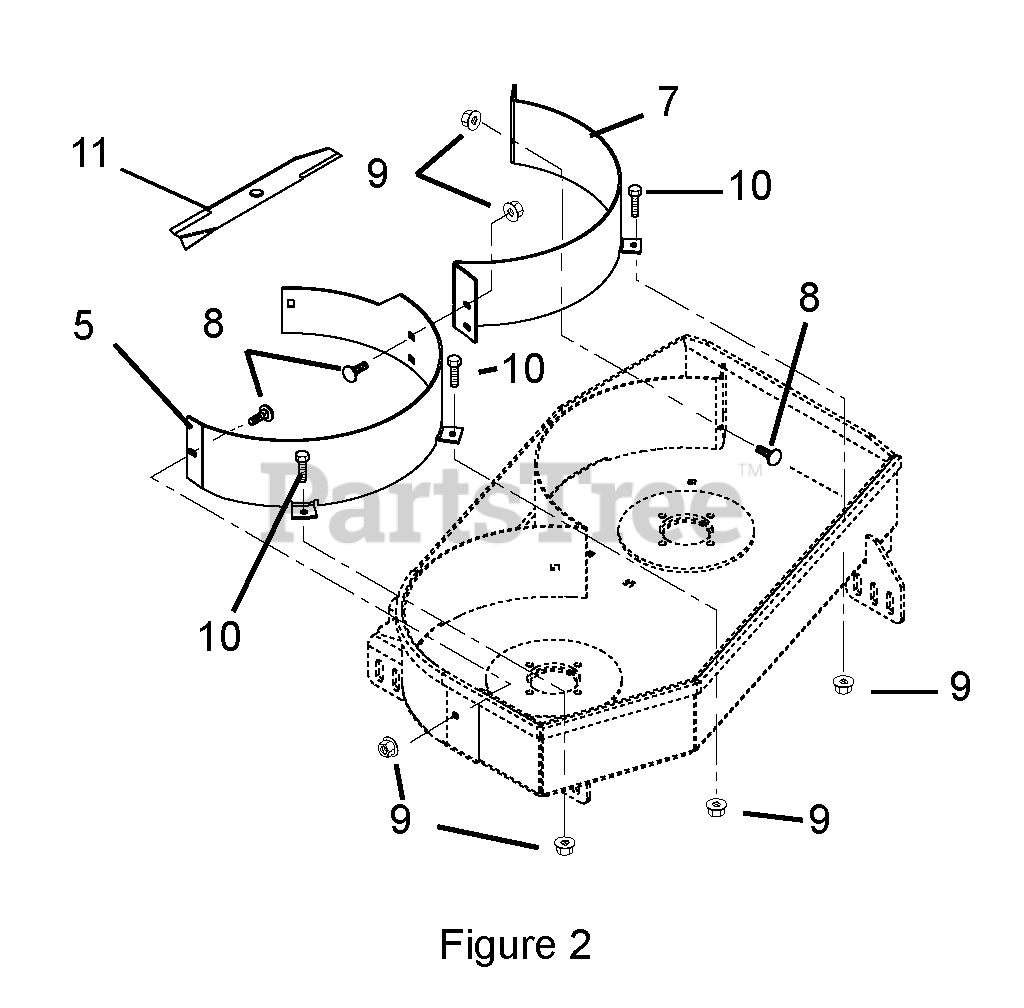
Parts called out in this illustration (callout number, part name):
5	BAFFLE-MULCH-LEFT FRONT-32"
5	BAFFLE-MULCH-LEFT FRONT-36"
5	BAFFLE-MULCH-LEFT FRONT-44"
5	BAFFLE-MULCH-LEFT FRONT-48"
5	BAFFLE-MULCH-LEFT FRONT-52"
5	BAFFLE, MULCH 34" FRONT LH
7	BAFFLE-MULCH-RIGHT FRONT-32"
7	BAFFLE-MULCH-RIGHT FRONT-36"
7	BAFFLE-MULCH-RIGHT FRONT-44"
7	BAFFLE-MULCH-RIGHT FRONT-48"
7	BAFFLE-MULCH-RIGHT FRONT-52"
7	BAFFLE, MULCH 34" FRONT RH
8	@BLT-RDHDSQNK .31-18X.75 G5YZ
9	@NUT-LK-TOP-FLG .31-18 YWZC
10	@BLT-HEX .31-18X.75 GR5 YWZC
11	BLADE, MULCH 16.25
11	BLADE, MULCH 18.00"
11	BLD,MULCHING 50" MWR
